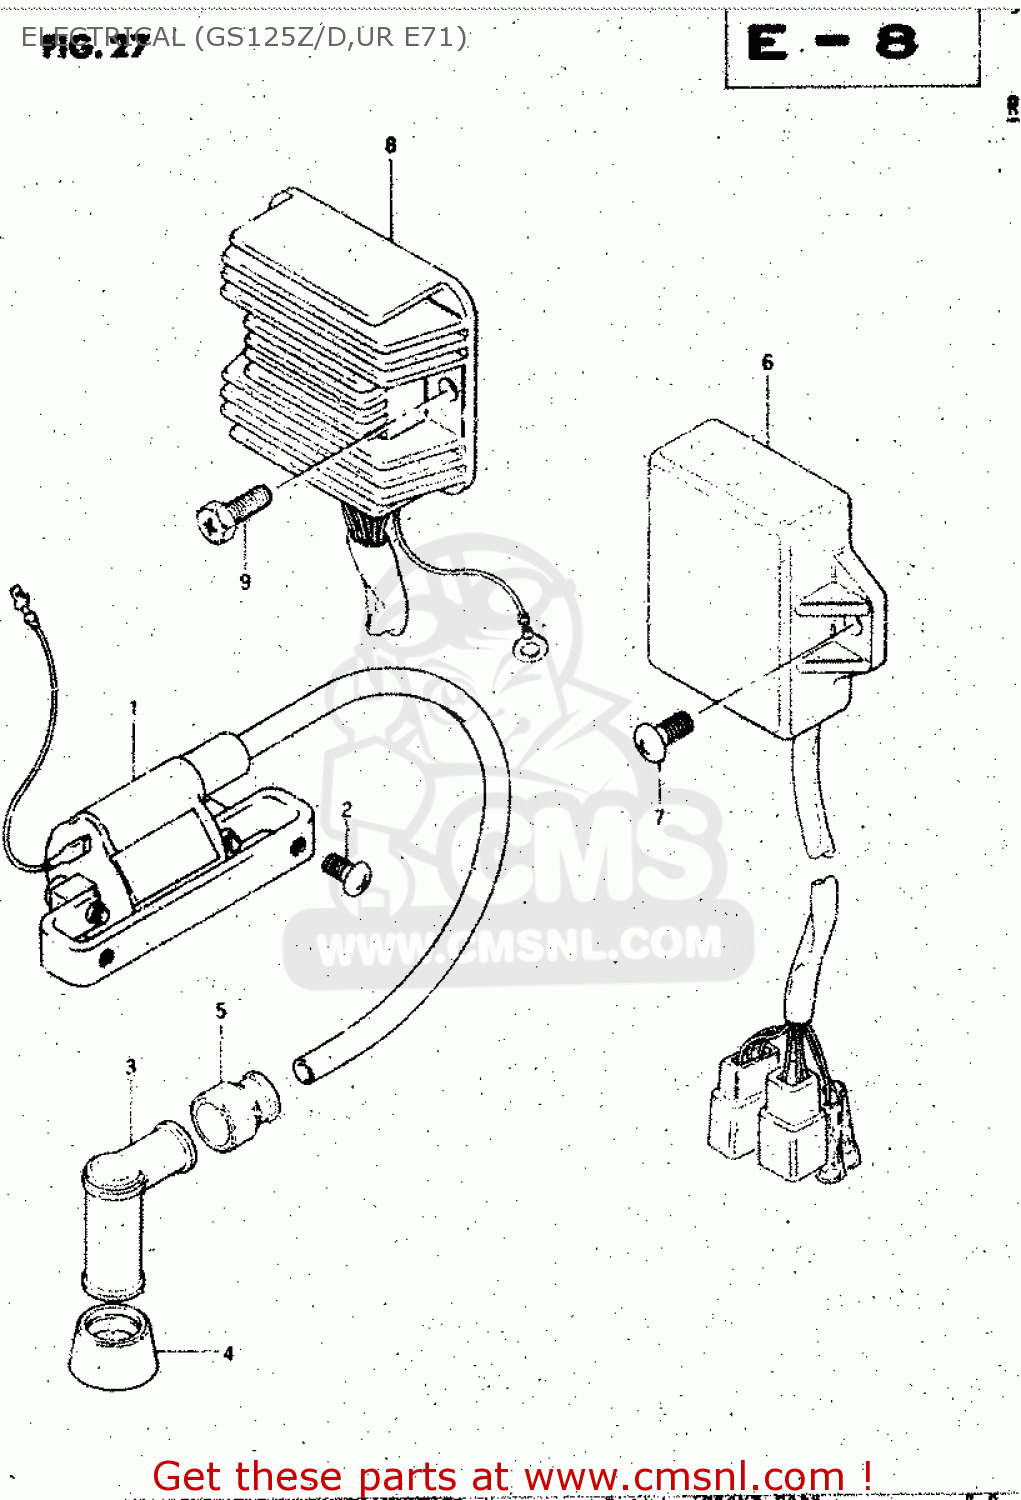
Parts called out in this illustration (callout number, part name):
1	COIL, IGNITION
2	SCREW
3	CAP ASSY,SPARK PLUG
4	SEAL,SPARK PLUG CAP
5	SEAL,HIGH TENSION CORD
6	CDI UNIT
7	SCREW
8	RECTIFIER ASSY
9	BOLT(6X20)
